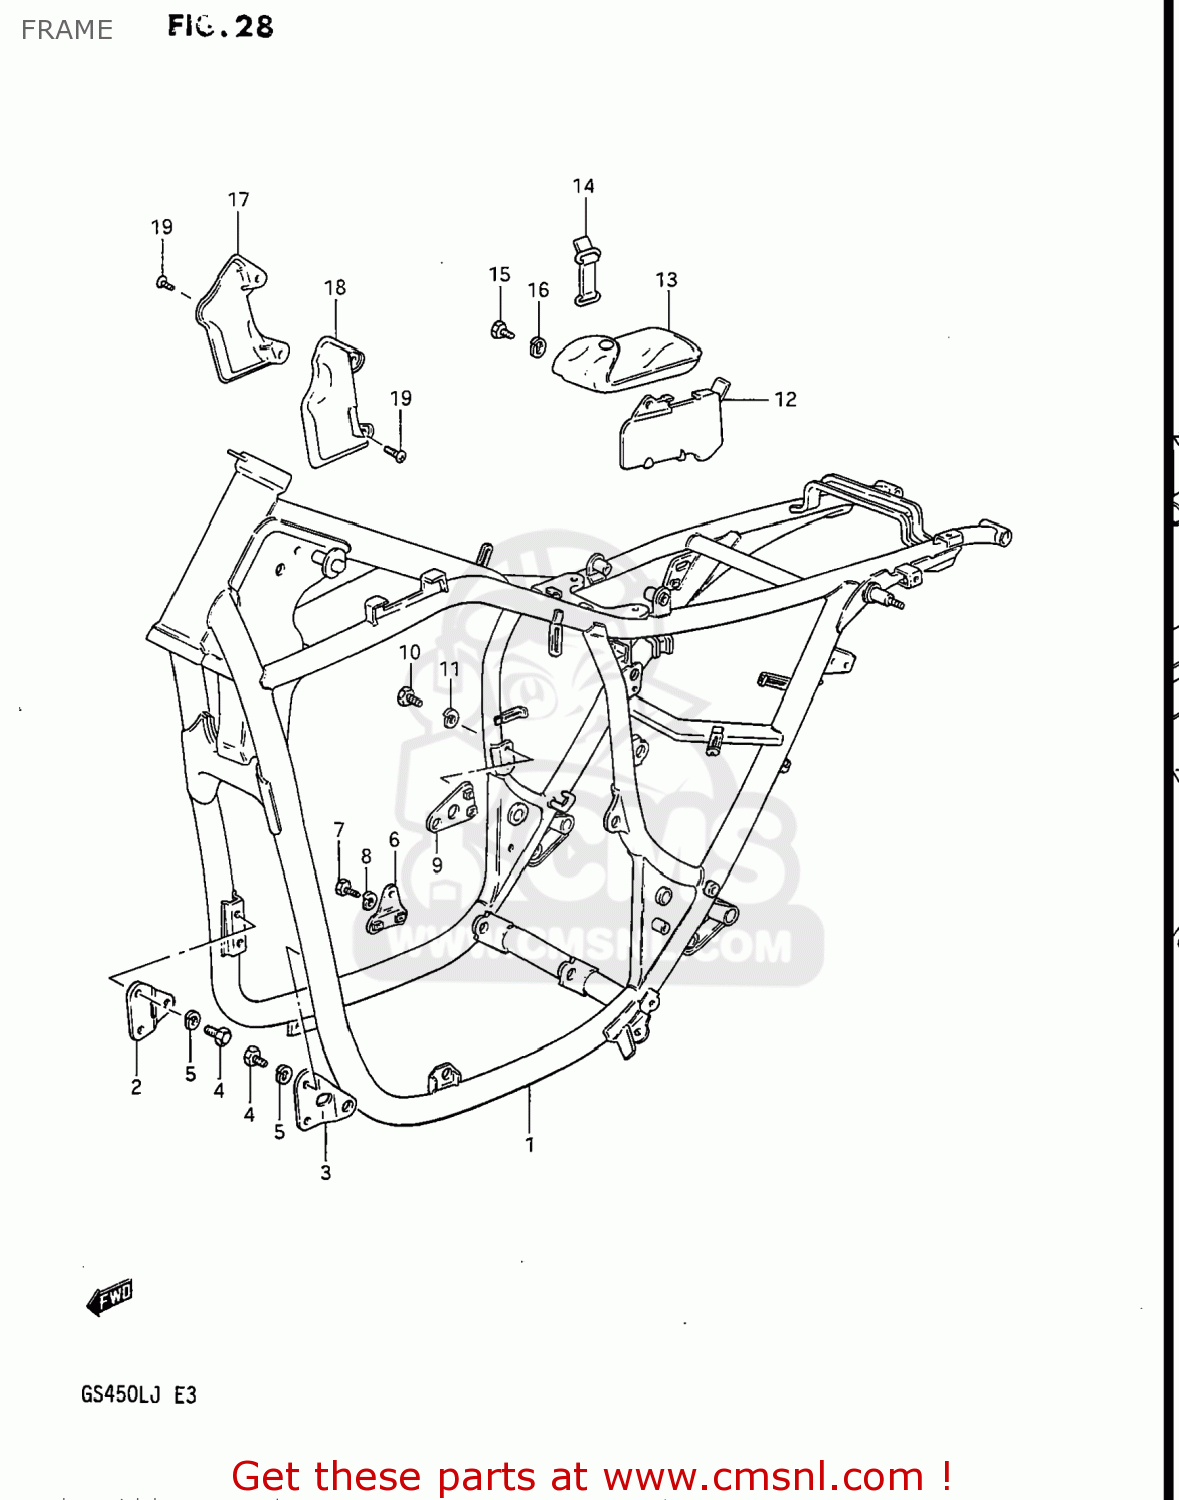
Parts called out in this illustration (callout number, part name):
1	FRAME
2	PLATE,ENG MTG NO.1,R
3	PLATE,ENGINE MOUNTING,LEFT
4	BOLT
5	WASHER,LOCK,8.
6	PLATE,MOUNTING NO.2,LEFT
7	BOLT
8	WASHER,LOCK,8.
9	PLATE,MOUNTING NO.4,LEFT
10	BOLT
11	WASHER,LOCK,8.
12	HOLDER,TOOL
13	TOOL SET
14	BAND
15	BOLT
16	WASHER,LOCK
17	COVER,FRAME HEAD,RIGHT
18	COVER,FRAME HEAD,LEFT
19	SCREW, FRONT & REAR
